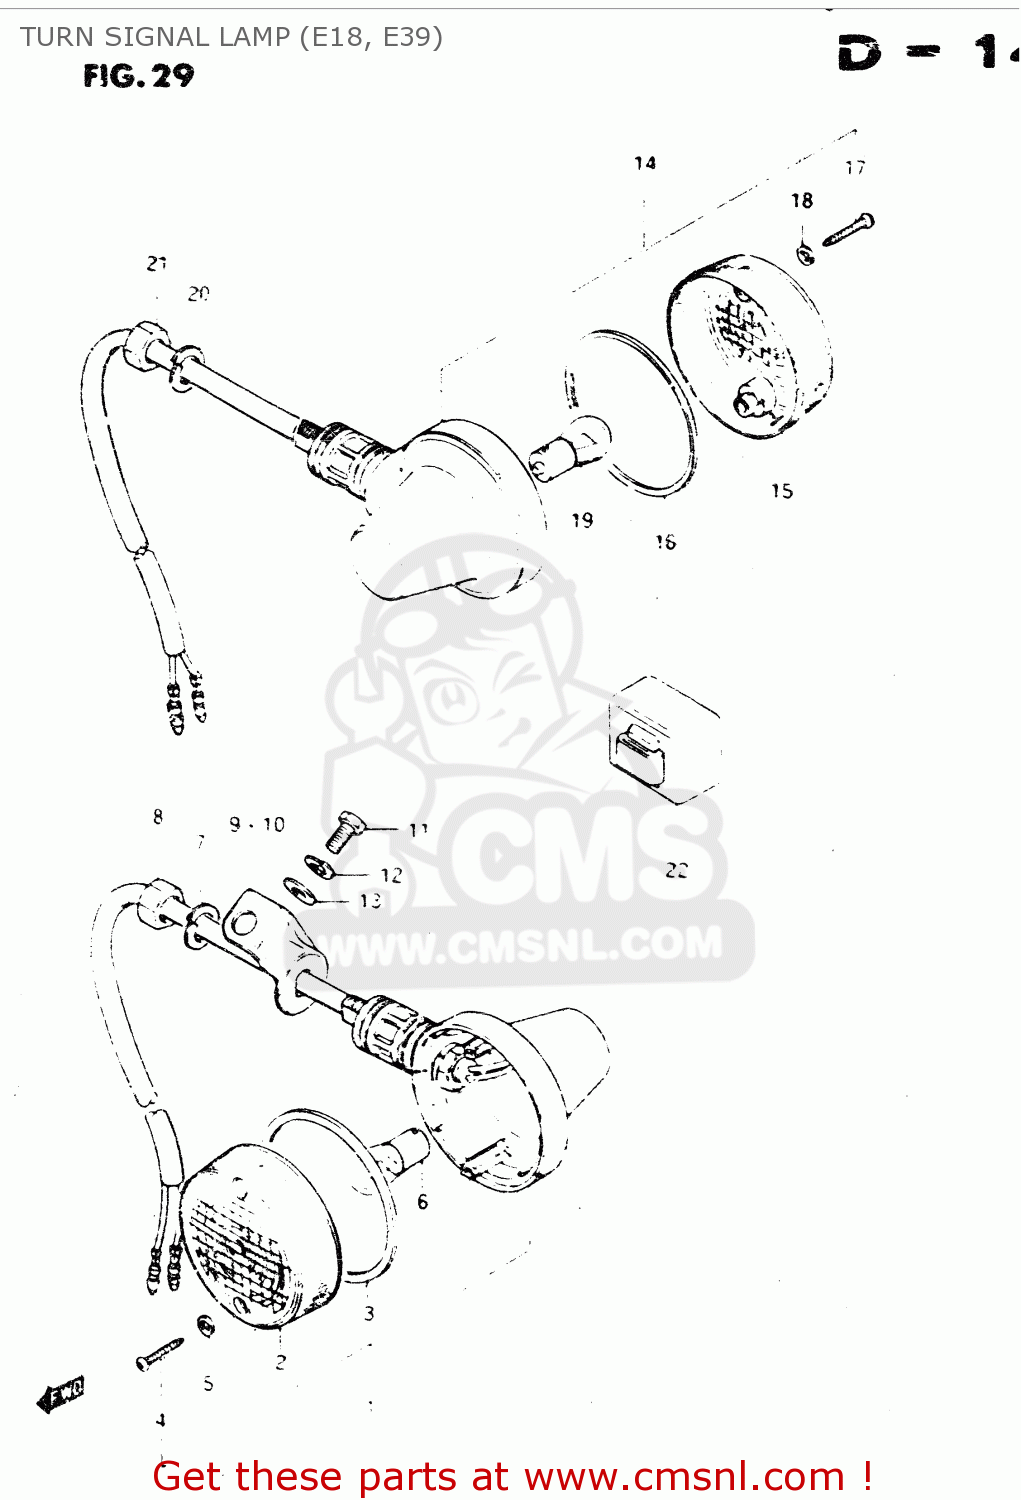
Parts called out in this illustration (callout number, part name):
1	LAMP, FRONT TURN SIGNAL
2	LENS
3	GASKET (NAS)
4	SCREW TAPP.
5	GASKET (NAS)
6	BULB(12V21W)
7	WASHER,LOCK 12
8	NUT
9	BRACKET,TURNSIGNAL LAMP,R
10	BRACKET,TURNSIGNAL LAMP,L
11	BOLT
12	LOCK WASHER
13	WASHER
14	LAMP, REAR TURN SIGNAL
15	LENS
16	GASKET (NAS)
17	SCREW TAPP.
18	GASKET (NAS)
19	BULB(12V21W)
20	WASHER,LOCK 12
21	NUT
22	RELAY,TURN SIGNAL
